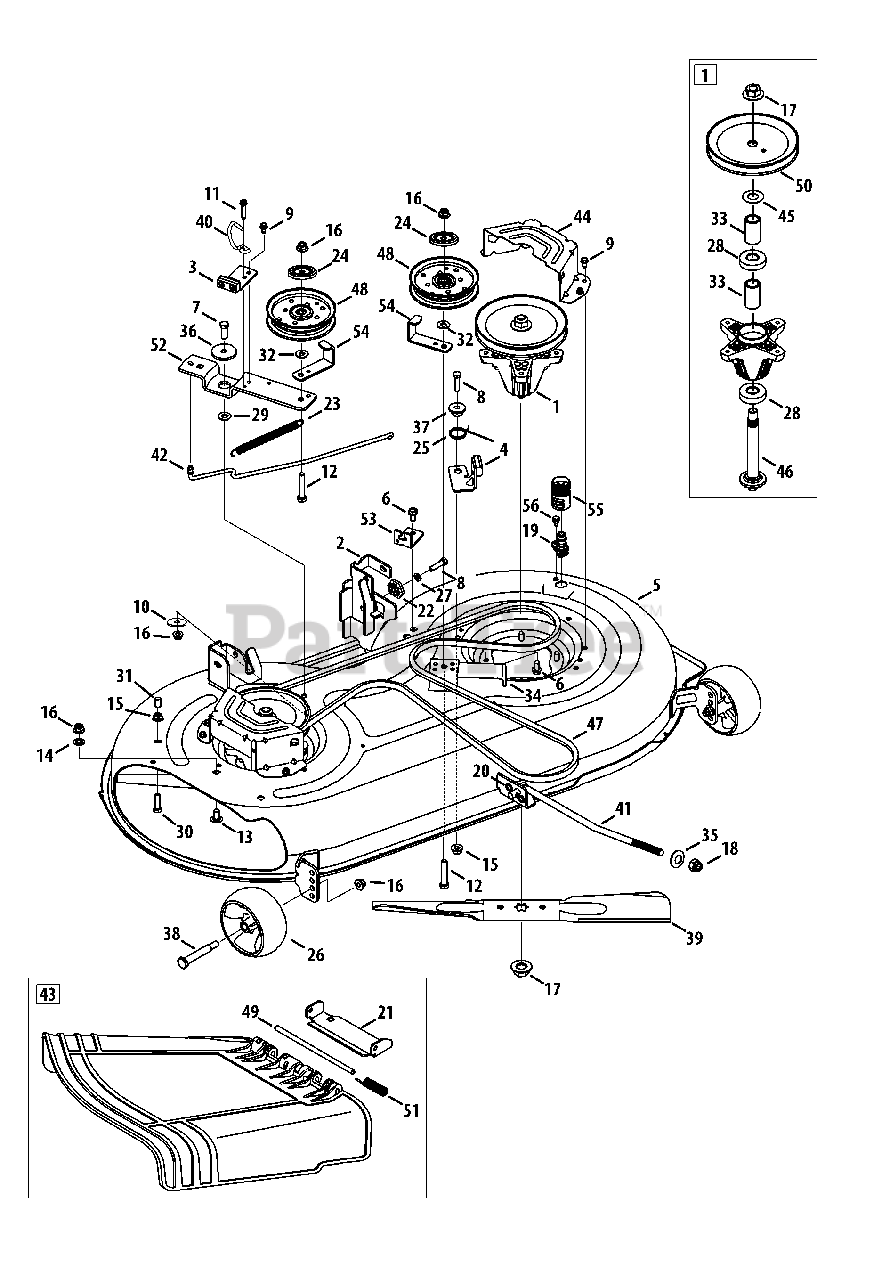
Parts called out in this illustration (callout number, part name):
1	Spindle Ass’y, Pulley, 6.3 Dia
2	Bracket Ass’y, Deck, Hanger LH
3	Brake Ass’y, Deck, 42/46
4	Brake Ass’y, Deck, 46"
5	Deck Ass’y, Offset, 42" W/O wheel
6	Screw, Self-tapping, 5/16-18, .750
7	Hex Screw, 3/8-16, 1.25, Gr5, Std
8	Hex Screw, 5/16-18, 1.25, Gr5, Std
9	Screw, Self-tapping, 1/4-20, 0.500
10	Flat Washer, .406 x 1.500 x .105
11	Screw, Self-tapping, 1/4-20, .750
12	Hex Screw, 3/8-16, 2.00, Gr5, Std
13	Bolt, Carriage, 3/8-16, 0.75, Gr1
14	Nut, Push, 3/8
15	Nut, Flange Lock, 5/16-18, Grf
16	Nut, Flange Lock, 3/8-16, Grf
17	Nut, Flange, 5/8-18
18	Nut, Lock, 1/2-13
19	Deck Wash Nozzle
20	Bow-Tie Cotter Pin
21	Chute Bracket
22	Gear, Deck, Adjustment
23	Spring, Extension, .62 Dia x 6.12
24	Pulley Cap
25	Spring, Torsion, .992 ID X 1.17 OD
26	Wheel, Deck, 5.0 Dia Ball
27	Washer, Lock, 5/16, Regular Duty
28	Bearing, Ball, .787id x 1.85 Odx.551
29	Washer, Flat, .385 X 1.0 X .030
30	Hex Cap Screw, 5/16-18 x 1.00
31	Cap, .290 x .500
32	Washer, Flat, .385 x .870 x .092
33	Spacer, .792 x 1.060 x 1.860
34	Bracket, Support, Stationary Idler
35	Deck Lift Pivot Cup
36	Spacer, Shoulder, .8840 x .190
37	Shoulder Spacer
38	Bolt, Shoulder, .496 x 2.50, 3/8-16
39	Blade, Cut, 21.23" 2-In-1, Econ
40	Rod, Keepr, Belt 42 Idler
41	Rod, Lift, Deck, Frt, 12.7
42	Rod, Control, Brake 42"
43	Chut Assembly, 42" Deck
44	Deck Belt Cover, 42
45	Washer, Flat, .760 Idx1.50 OD
46	Shift, Spindle, 6.11.
47	Belt, V Type, A Sec X 96.5
48	Pulley, Idler, 4.25"Dia
49	Pin, Hinge, Dia .3125 x 7.96
50	Pulley, Deck, 6.3 Dia
51	Spring, Torsion, .44 I.D. X 2.0
52	Pivot idler Bracket, 46
53	Bracket, Cable, Deck Engage
54	Bracket, Guard, Belt, 4.25 Pulley
55	Water Nozzle Adapter
56	Shoulder Screw, 1/4-20 x 0.50
